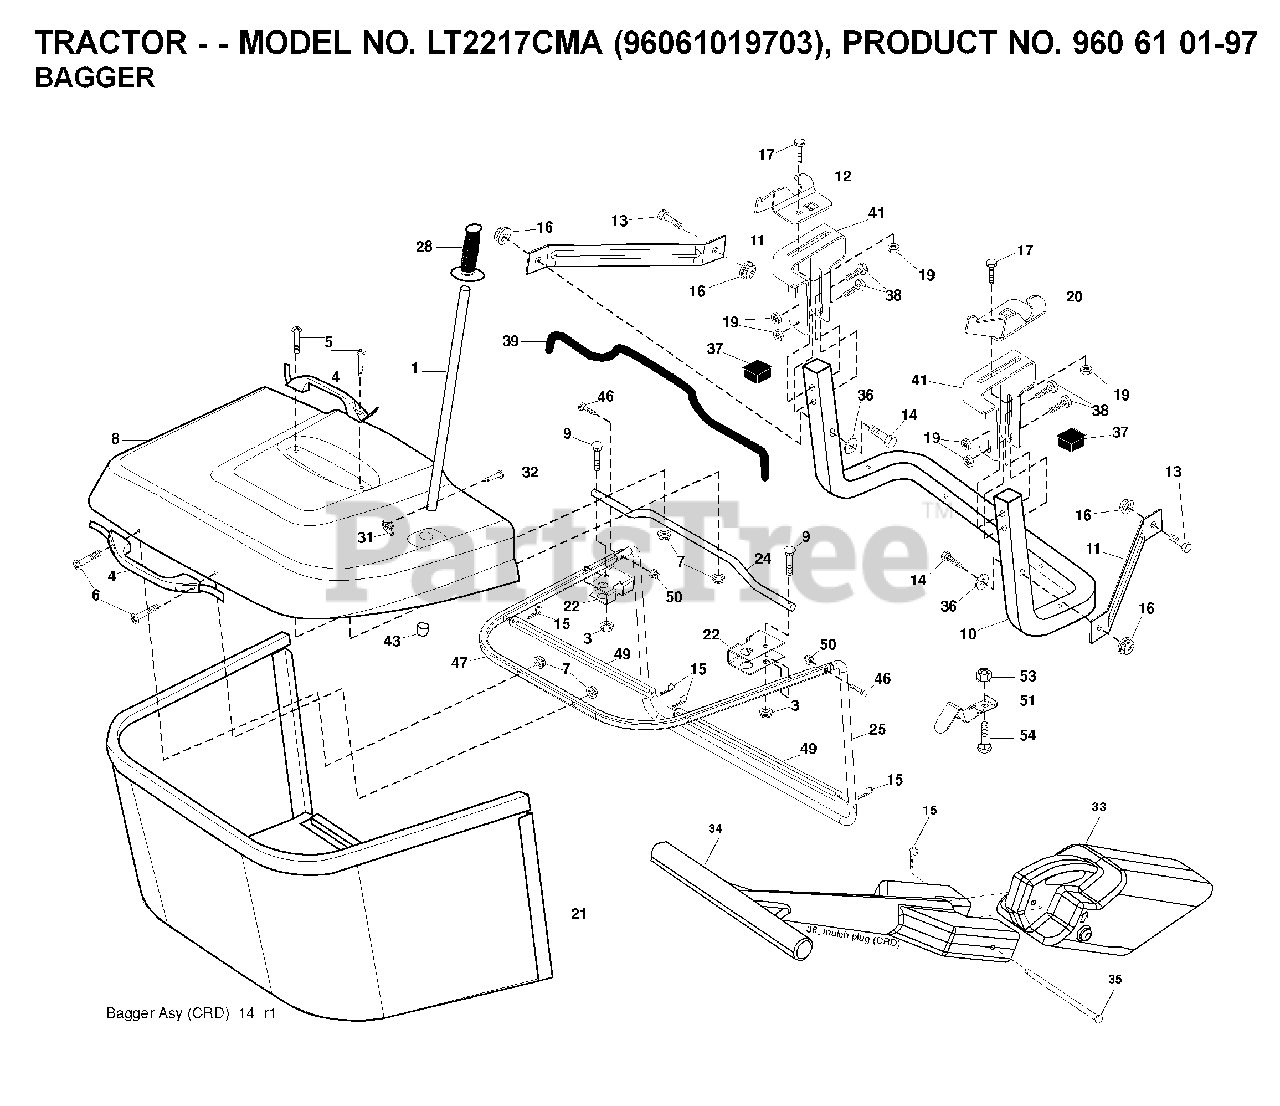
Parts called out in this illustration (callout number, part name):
1	TUBE HANDLE
3	NUT T
5	SCREW.PAN.HEAD
11	BRACKET
14	BOLT-HEX EAK
15	RETAINER-SPRNG RB
16	NUT LOCK FLG 3/8-16 UNC
17	BOLT
19	NUT LOCK HEX FLANGE 5/16-18
20	BRKT.PIVOT.RH.CRD
21	BAGGER.ASM.CRD.2007
22	BRACKET
24	TUBE
28	GRIP.HANDLE.BLACK
31	RETAINER CLIP
32	RIVET,DRILLED
33	PLUG
35	PIN
38	BOLT.5/16-18X2.5
39	SEAL.BAGGER.CRD
41	BRKT, BAGGER
43	PLUG, TUBING END
46	BOLT.CARRIAGE.5/16-18
50	NUT.71038.31-18.HEX.NYLOCK
53	NUT
54	BOLT
